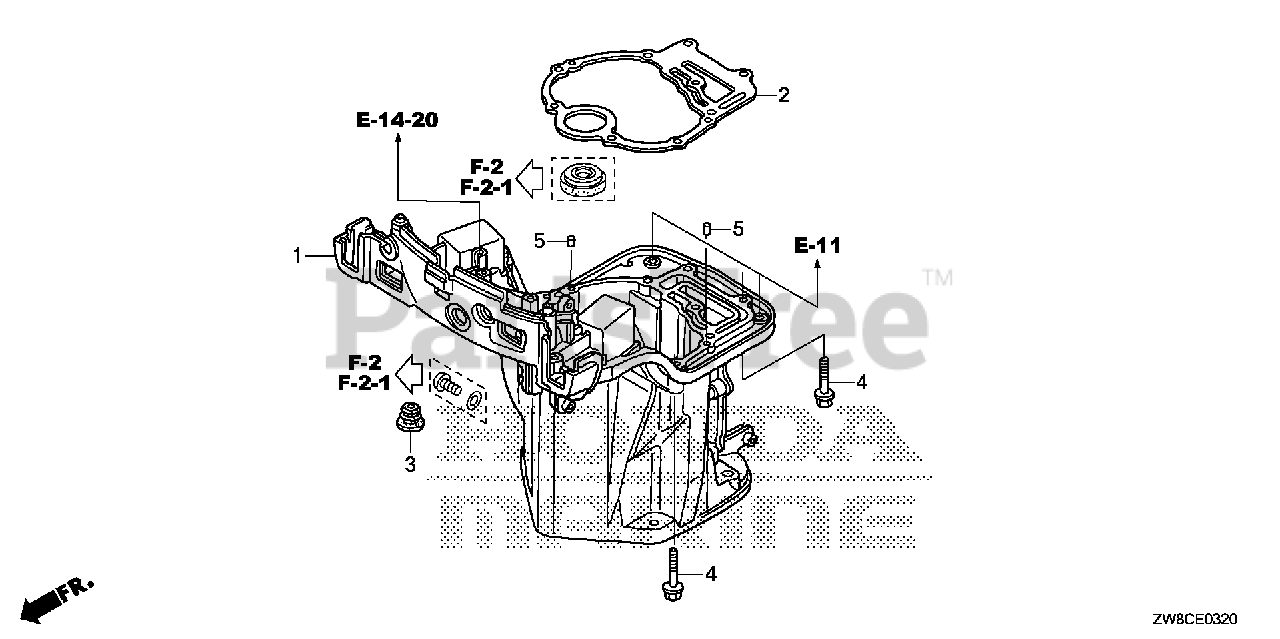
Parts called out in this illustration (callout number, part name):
1	CASE, OIL *NHB14M* (AQUA MARINE SILVER METALLIC)
2	GASKET, OIL PAN
3	GROMMET, WATER TUBE
4	BOLT, FLANGE (8X35)
5	PIN, DOWEL (6X10)
